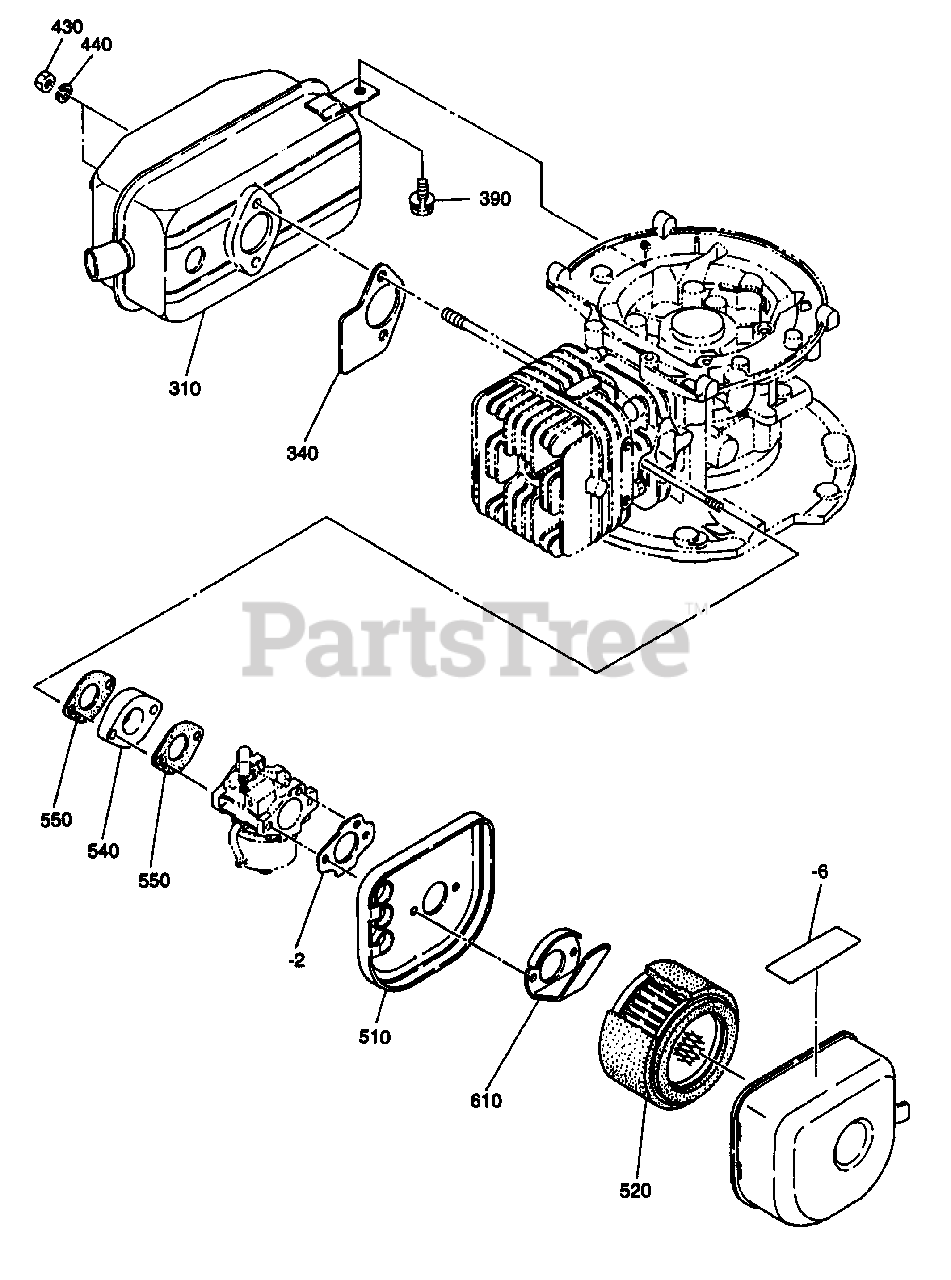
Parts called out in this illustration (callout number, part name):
2	GASKET (AIR CLEANER)
340	GASKET CP (EXHAUST)
390	BOLT & WASHER ASSY
440	SPRING WASHER
510	AIR CLEANER ASSY
520	ELEMENT SET
550	GASKET (INSULATOR)
610	GUIDE PLATE, CLEANER
